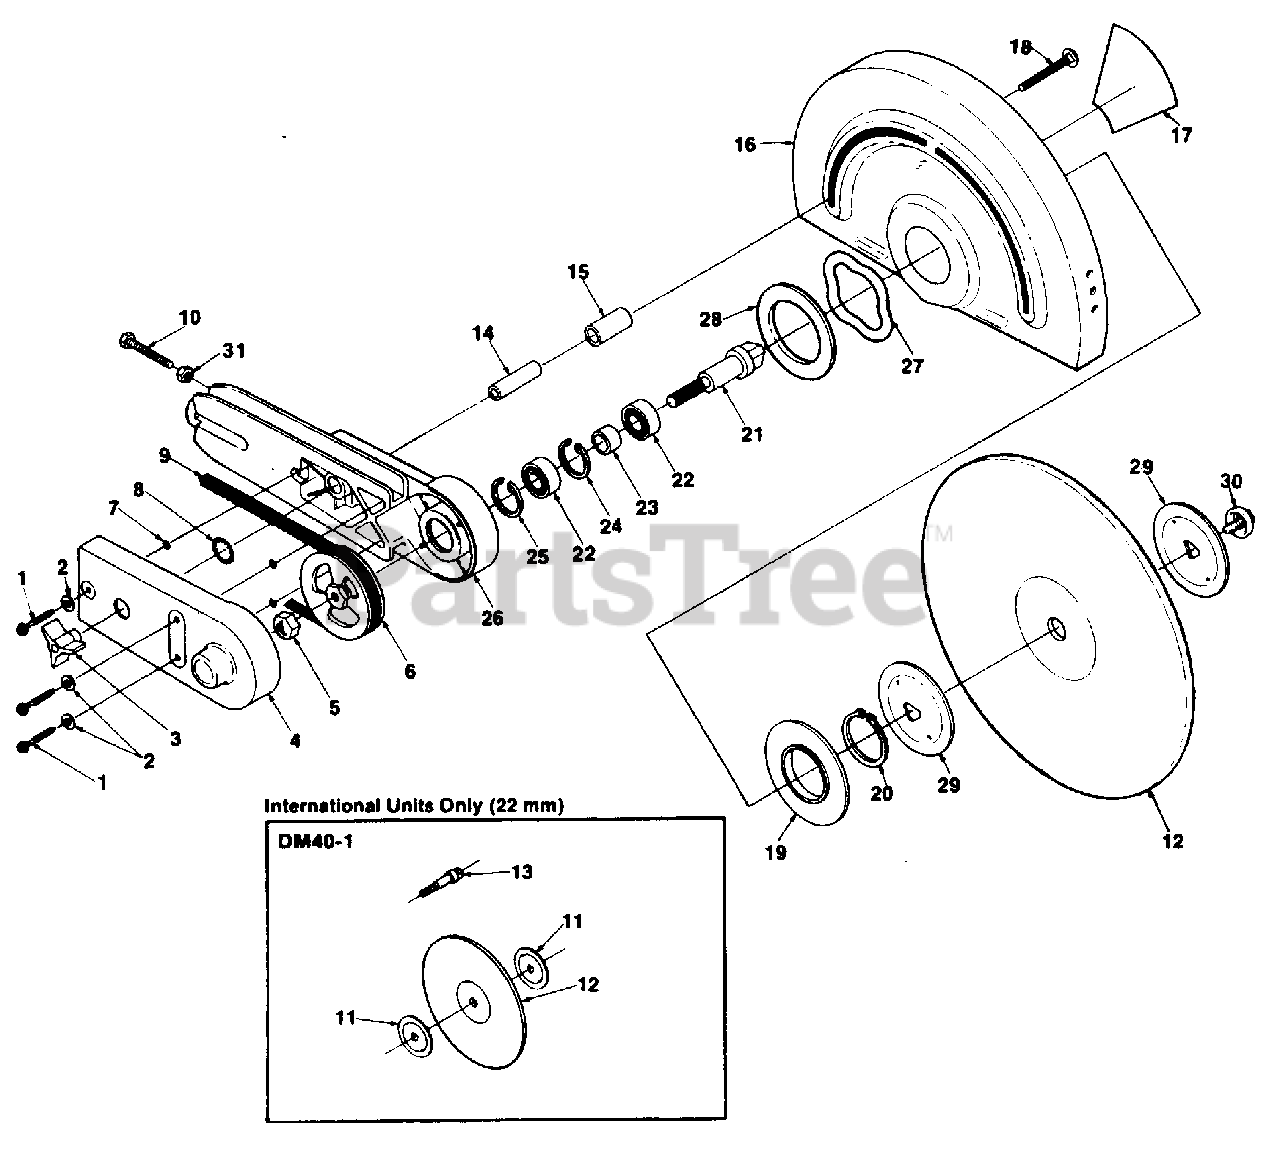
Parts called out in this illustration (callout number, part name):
2	WASHER- Flat
3	KNOB
4	COVER- Arm
5	NUT- Lock hex
6	PULLEY- Driven
7	"O" RING
8	RING- Retaining
9	BELT-"V" Drive
11	FLANGE-Wheel (DM-40-1)
12	WHEEL- Resinoid (Concrete) (DM40)
13	SHAFT- Wheel (DM40-1)
14	SPACER- Guard adjusting
15	TUBING- Rubber
16	GUARD- Wheel
17	LABEL- Caution
18	BOLT- Step
19	WASHER- Mounting
21	SHAFT-Wheel (DM40)
22	BEARING- Ball
23	SPACER- Bearing
24	RlNG-Retaining
25	RING- Retaining
26	ARM- Wheel
27	SPRING- Wave
29	FLANGE-Wheel (DM40)
30	SCREW, WASHER & RETAINER KIT
